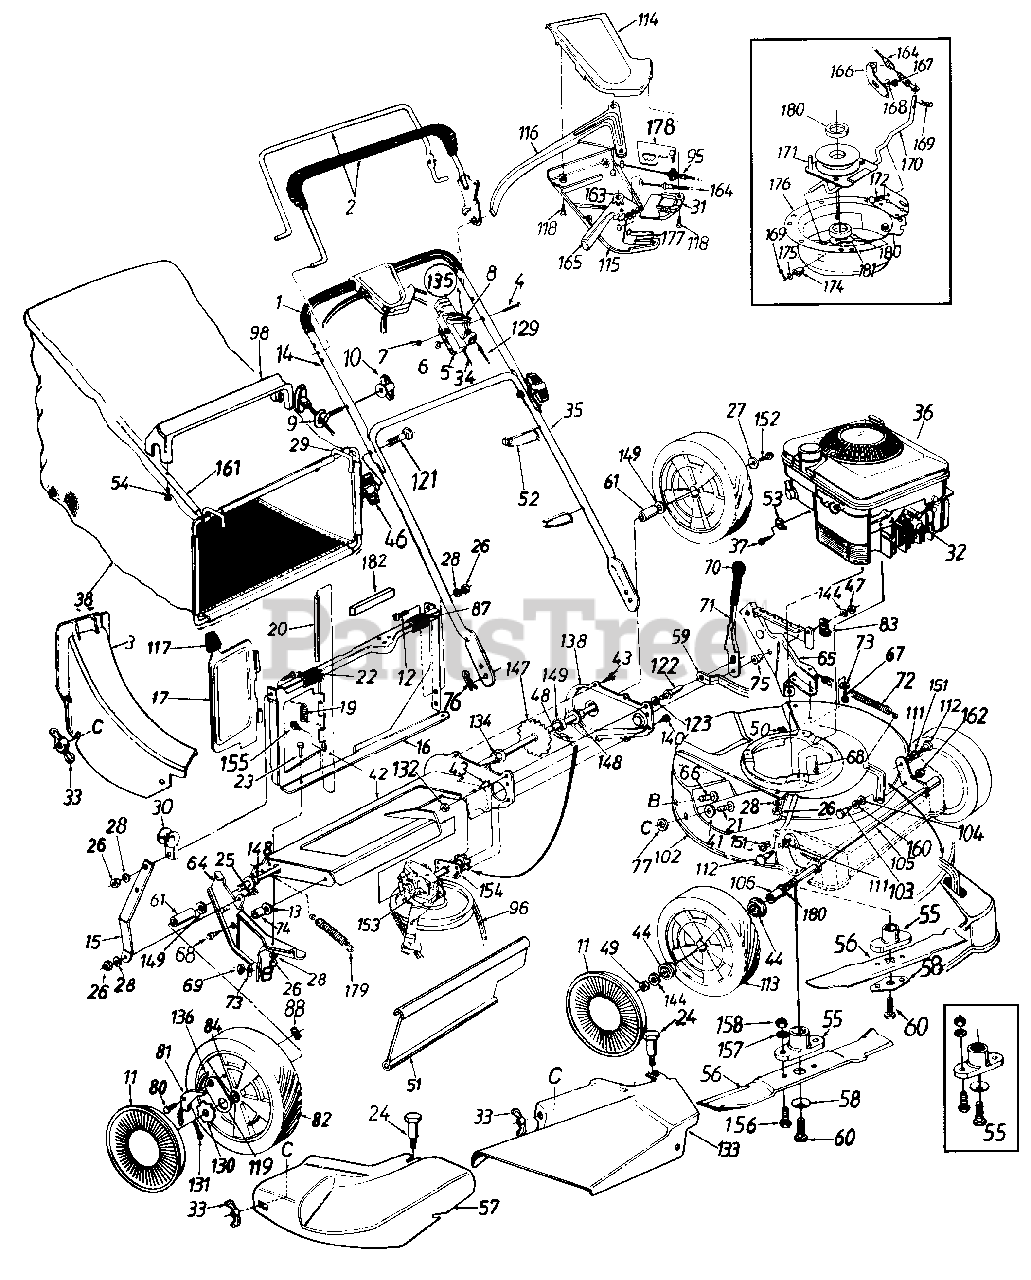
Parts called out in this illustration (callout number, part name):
1	Foam Grip
3	Rear Discharge Chute Ass'y.
4	Oval C-Sunk Scr.
5	Throttle Body
6	Spr. Wash. .66" I.D.
7	Hex L-Nut 1/4-20 Thd.
8	Throttle Lever
9	Rope Guide
10	Handle Knob 1/4-20 Thd.
11	Hub Cap
12	Truss Mach. Scr. 1/4-20 x .62" Lg.
13	Fl-Wash. .383" I.D. x 1" O.D.
20	Pivot Pin
21	Carriage Bolt 1/4-20 x .62"
22	Truss Mach. Scr. 1/4-20 x 3/4" Lg.
23	Hex AB-Tap Scr. 1/4 x .38" Lg.
24	Shoulder Bolt .312 Dia. x .18 Lg. - Special
25	Hex Bolt 1/4-20 x .62" Lg.
26	Hex Nut 1/4-20 Thd.
27	Bell-Wash. 1/4" I.D.
28	L-Wash. 1/4" I.D.
30	Rope Guide
31	S.P. Control Cover
32	Spark Plug Insulator
33	Wing Nut w/Washer
34	Throttle Control Wire 61"
36	Engine
37	Hex Self-Tap Scr. #10-32 x .62" Lg.
38	Grass Bag (Plain)
41	Fl-Wash. .344" I.D. x .62"
44	Ball Bearing
46	Hand Knob
47	Hex Patch L-Nut 3/8-24 Thd.
48	#48 Chain .500" Pitch x 30 Links
49	Hex L-Nut 1/2-20 Thd.
51	Rear Flap 4.8" x 18" Lg.
52	Cable Tie
53	Cable Clamp
54	Hex AB Scr. #12 x 1.25" Lg.
55	Blade Adapter Kit
56	21" Mulching Blade
57	Mulching Plug
58	Bell-Wash. .39" I.D.
59	Height Adj. Connecting Arm
60	Hex Bolt 3/8-24 x 1.5" Lg.
61	Spacer .513" I.D. x .703" O.D. x .69" Lg.
67	Hex Wash. Hd. B-Tap Scr. 5/16-18
68	Hex Wash. Hd. TT-Tap Scr. 3/8-16
69	Hex Nut 5/16-18 Thd.
71	Height Adj. lever
72	Extension Spring .75" O.D. x 8" Lg.
73	Bell-Wash. 5/16" I.D.
74	Spacer
75	Shld. Spacer .500" Dia.
76	Hairpin Clip
77	Bolt Retainer 1/4 x 50" O.D.
80	Shld. Scr. .342" Dia. x .268
81	Pawl - R.H.
82	Rear Wheel Ass'y. Comp.
83	Clamp
84	Bearing 1/2" I.D.
87	Panel Clip
88	Weld L-Nut 1/4-20 Thd.
95	S.P. Cable
96	"V"-Belt
98	Bag Handle
102	21" Deck Ass'y.
103	Shld. Bolt .5" Dia. x .295
104	Bell-Wash. .515" I.D. x 1.0" O.D.
105	Front Axle Ass'y
106	Sleeve .526" I.D. x .690" O.D. x .880" Lg.
111	Intern. L-Wash. 3/8 I.D.
112	Shld. Bolt .575" Dia. x .42
113	Front Wheel Ass'y. Comp.
114	Self-Propelled Control Cover
115	Self-Propelled Control Cover
116	Control Lever
117	Door Grip
118	Fl - "C"-Sunk Hd. Tap Scr. #10 x .75" Lg.
119	Pawl Plate
121	Curved hd. Bolt 5/16-18 x 2" Lg.
122	Shld. Pin 3/8-24 x 1.43" Lg.
123	L-Wash. 3/8" I.D.
129	Control Cable 43" Lg.
130	Ratchet Wheel 1.62" O.D.
131	Cotter Pin 1/8" Dia. x 1.00" Lg.
132	Hex Jam Nut 3/8-24 Thd.
133	Side Chute Deflector Ass'y.
134	Hex Flange Bearing
135	Throttle Box Comp.
136	Spring - Nylon
144	Fl-Wash. .385" I.D. x .87"
147	Rear Shaft Ass'y. 21.94" Lg.
148	Hex Flange Bearing .506" I.D. Plastic
149	Fl-Wash. .531" I.D. x .930"
151	Flanged Nyliner Brg.
152	Hex Bolt 1/4-20 x .62" Lg. (Grade 5)
153	Transmission Comp. (See Breakdown)
154	Hex Bearing Cup
155	Hex B-Tap Scr. #10 x .38
156	Hex Scr. 3/8-24 x 1.0" Lg.
157	L-Wash. 3/8" I.D.
158	Hex Nut 3/8-24 Thd.
160	Fl-Wash. .51" I.D. x .75" O.D.
162	Hex Jam Nut 3/8-16 Thd.
163	3 Tooth Rack Gear Insert
164	Spd. Control Cable - 50" Lg.
165	6-Spd. Shift Lever
168	Hex Cent. L-Nut 1/4-20 Thd.
169	Cot-Pin 3/32" Dia. x .75" Lg.
170	Shift Rod
171	Pulley Ass'y.
172	Carr. Bolt 1/4-20 x .50" Lg.
174	Flanged Bushing
175	Fl-Wash. .382" I.D. x .68" O.D.
178	6-Speed Rack Cable Brkt.
179	Ext. Spring 3.8" Lg.
180	Spacer .885" I.D. x 1" O.D.
181	Wave Wash. .88" I.D. x 1.38" O.D.
182	Foam Strip
17055B-0637	AXLE ASSY-CHAIN - POWDER BLACK (0637)
17055B-0638	AXLE ASSY-CHAIN - MTD/TROY-BILT RED (0638)
17055B-0665	AXLE ASSY-CHAIN - YARDMAN GREEN (0665)
